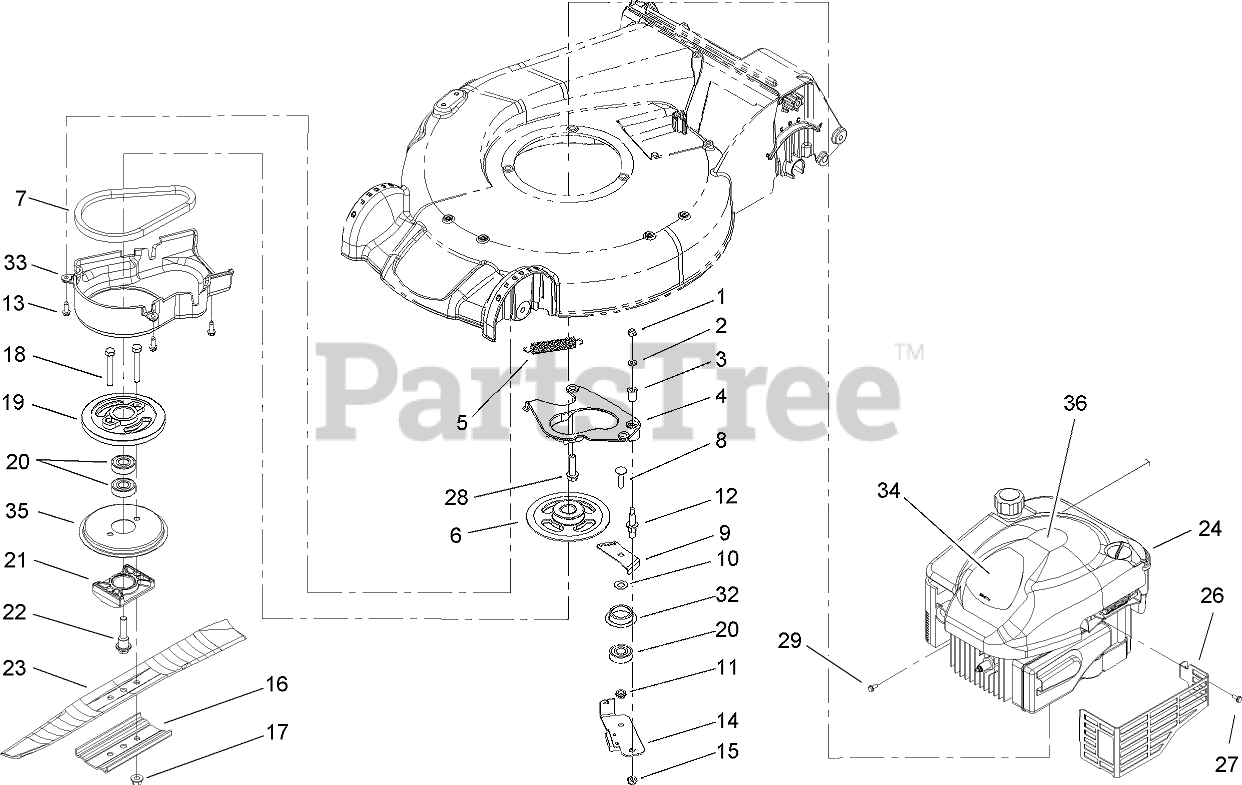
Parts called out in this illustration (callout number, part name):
1	NUT-LOCK, NI
2	WASHER-FLAT
3	BUSHING
4	PLATE-ANCHOR
5	SPRING-TENSION, BRAKE
6	PULLEY
7	BELT
8	BOLT-CARR
9	PLATE-GUIDE
10	WASHER-PLAIN
11	SPACER-BEARING
12	BOLT-SHOULDER
13	SCREW-HWHTF
14	BRAKE ARM ASM
16	SUPPORT-BLADE
17	NUT-LOCK
18	SCREW-HH
19	DRUM
20	BEARING-BALL
21	SUPPORT-BLADE
22	BOLT-CRANK
23	BLADE-BAGGING
23	BLADE-RECYCLING
26	SHIELD-MUFFLER
27	SCREW-TAPTITE
28	SCREW-HWH
29	SCREW-HWH
32	RETAINER-BELT
35	DISC
36	DECAL-RECOIL
